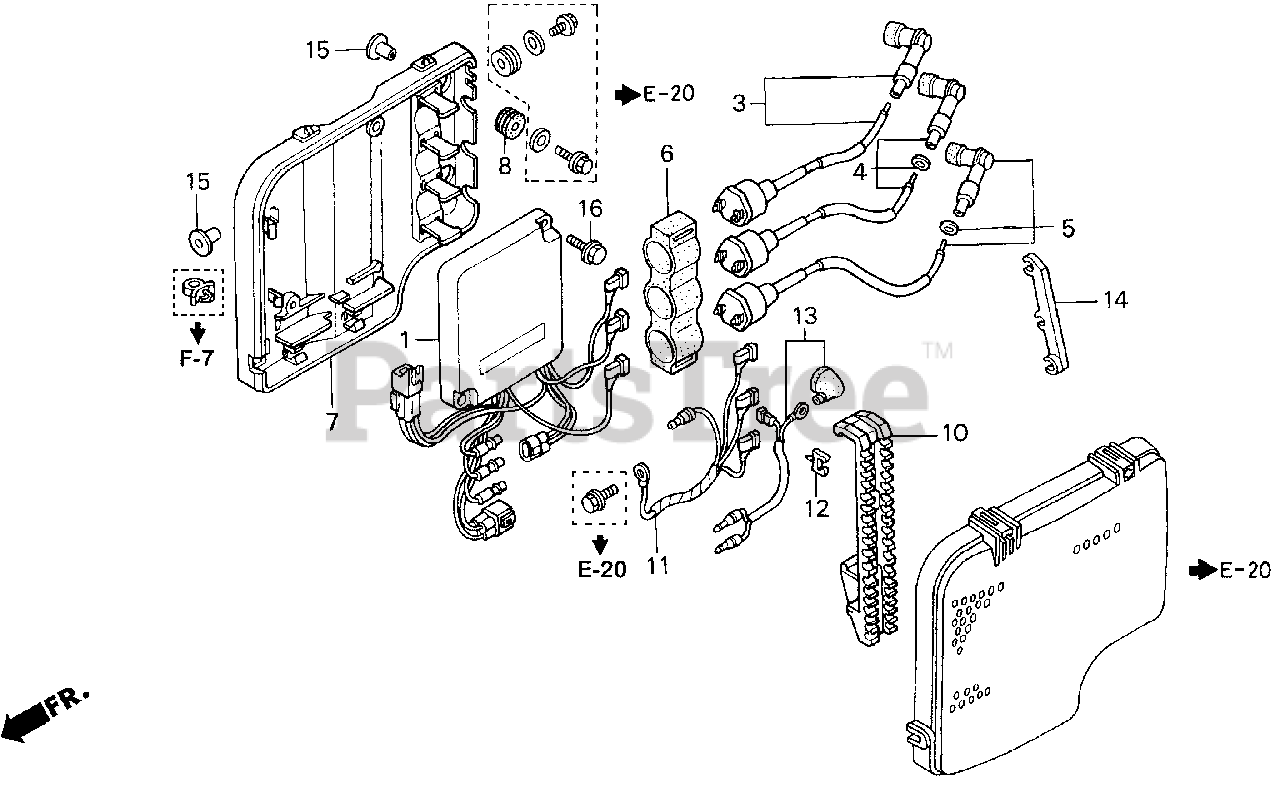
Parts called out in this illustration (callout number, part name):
1	MODULE, IGNITION CONTROL (CDI)
3	COIL, IGNITION (1)
4	COIL, IGNITION (2)
5	COIL, IGNITION (3)
6	SUSPENSION, IGNITION COIL
7	CASE, IGNITION CONTROL MODULE
8	GROMMET, IGNITION CONTROL MODULE CASE (B)
10	BRACKET, CONNECTOR (A)
11	WIRE ASSY., GROUND
12	CLIP, TURN SIGNAL WIRE
13	WIRE, SWITCH
14	CLIP, IGNITION WIRE
15	COLLAR, IGNITION CONTROL MODULE CASE
15	COLLAR, MODULE IGNITION CONTROL CASE (CDI)
16	BOLT, FLANGE (6X20)
